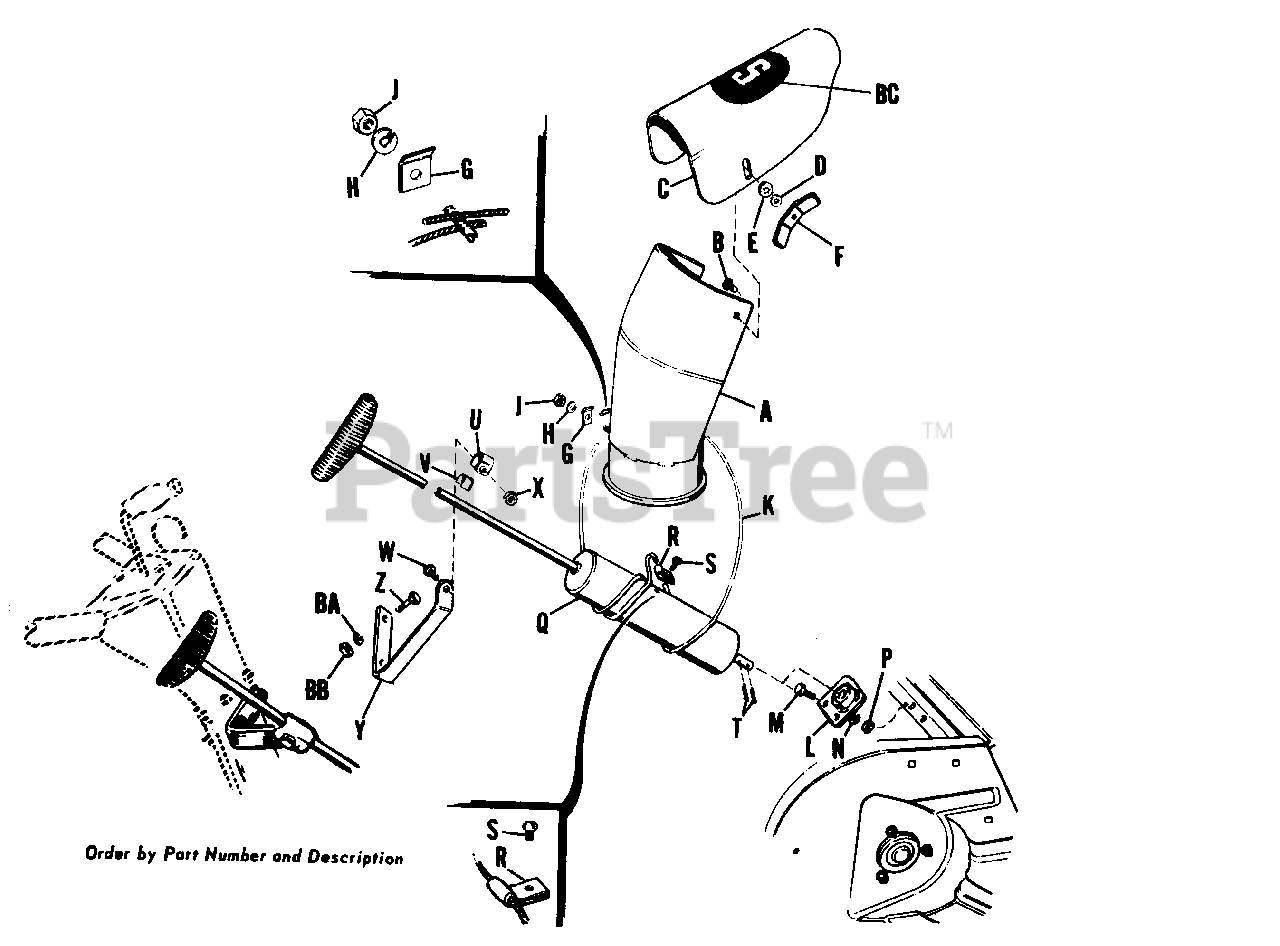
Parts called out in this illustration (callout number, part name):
A	Spout Assembly
B	Carriage Bolt, 5/16"-18 x 3/4" long
C	Spout Extension
D	Plain Washer, 3/8"
E	Lock Washer, 3/8"
F	NUT, Wing, 5/16-18
H	Lock Washer, 5/16"
J	Hex Nut, Full, 5/16"-18
K	Spout Cord
M	Hex Caps crew, 1/4"-20 x 5/8" long
N	Lock Washer, 1/4"
P	Hex Nut, Full, 1/4"-20
Q	Tube Assembly, Spout Control
S	Self-Tapplng Screw, 1/4"-20 x 1/2"
T	Cotter Pin, 1/8" x 3/4" long
U	Guide Rod
V	Liner, Guide
W	Hex Capscrew, 5/16"-18 x 1-1/4" long
X	Hex Nut, Full, Lock, 5/16"-18 NC
Y	Support, Spout Adj. Rod
Z	Hex Capscrew, 1/4"-20 x 1-3/4" long
BA	Lock Washer, 1/4"
BB	Hex Nut, Full, 1/4"-20
